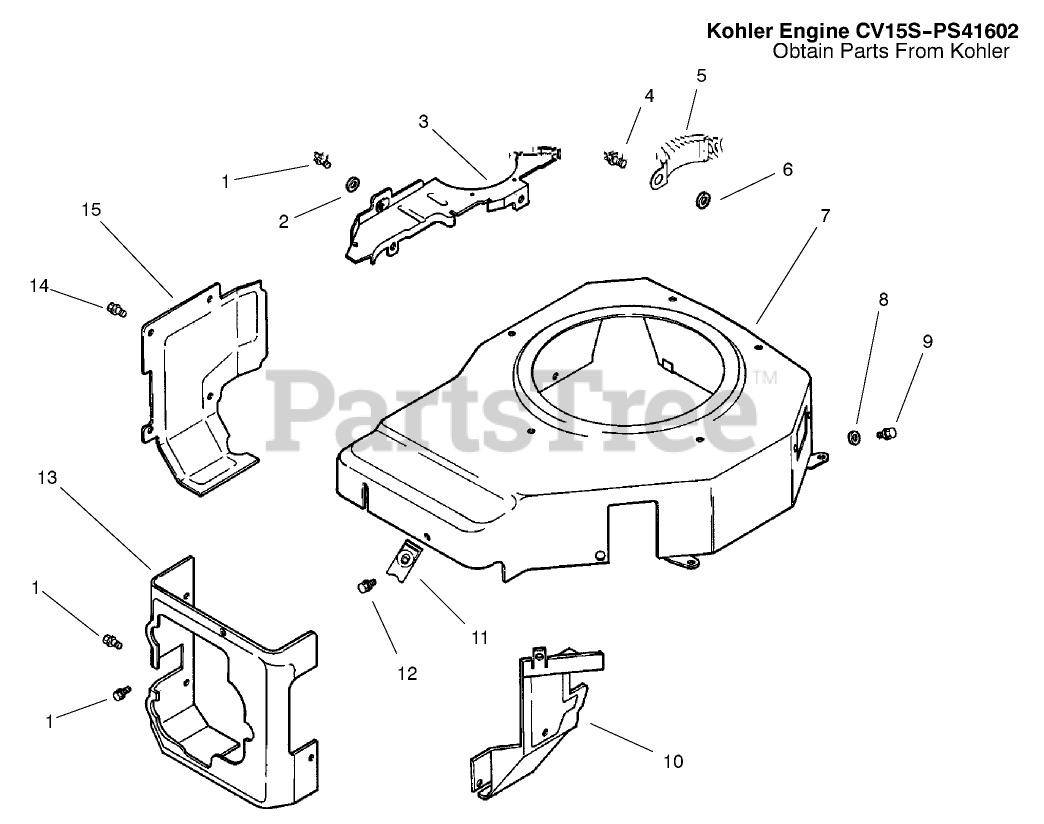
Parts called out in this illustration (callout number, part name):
1	Screw (M5x0.8x10)
3	Plate-Blower Housing (Only On: 72042,72043,72062,72063)
4	Screw-HHF
5	Cover-Pinion
6	Washer
7	Housing-Blower
8	Washer
10	Baffle-Carburetor (Only On: 72042, 72043, 72062, 72063)
12	Screw M5x0.8x20
13	Baffle-Cylinder Head (Only On: 72042, 72063, 72062, 72043)
14	Screw-Hex, Flange
15	Baffle-Cylinder Barrel (Only On: 72042, 72063, 72062, 72043)
